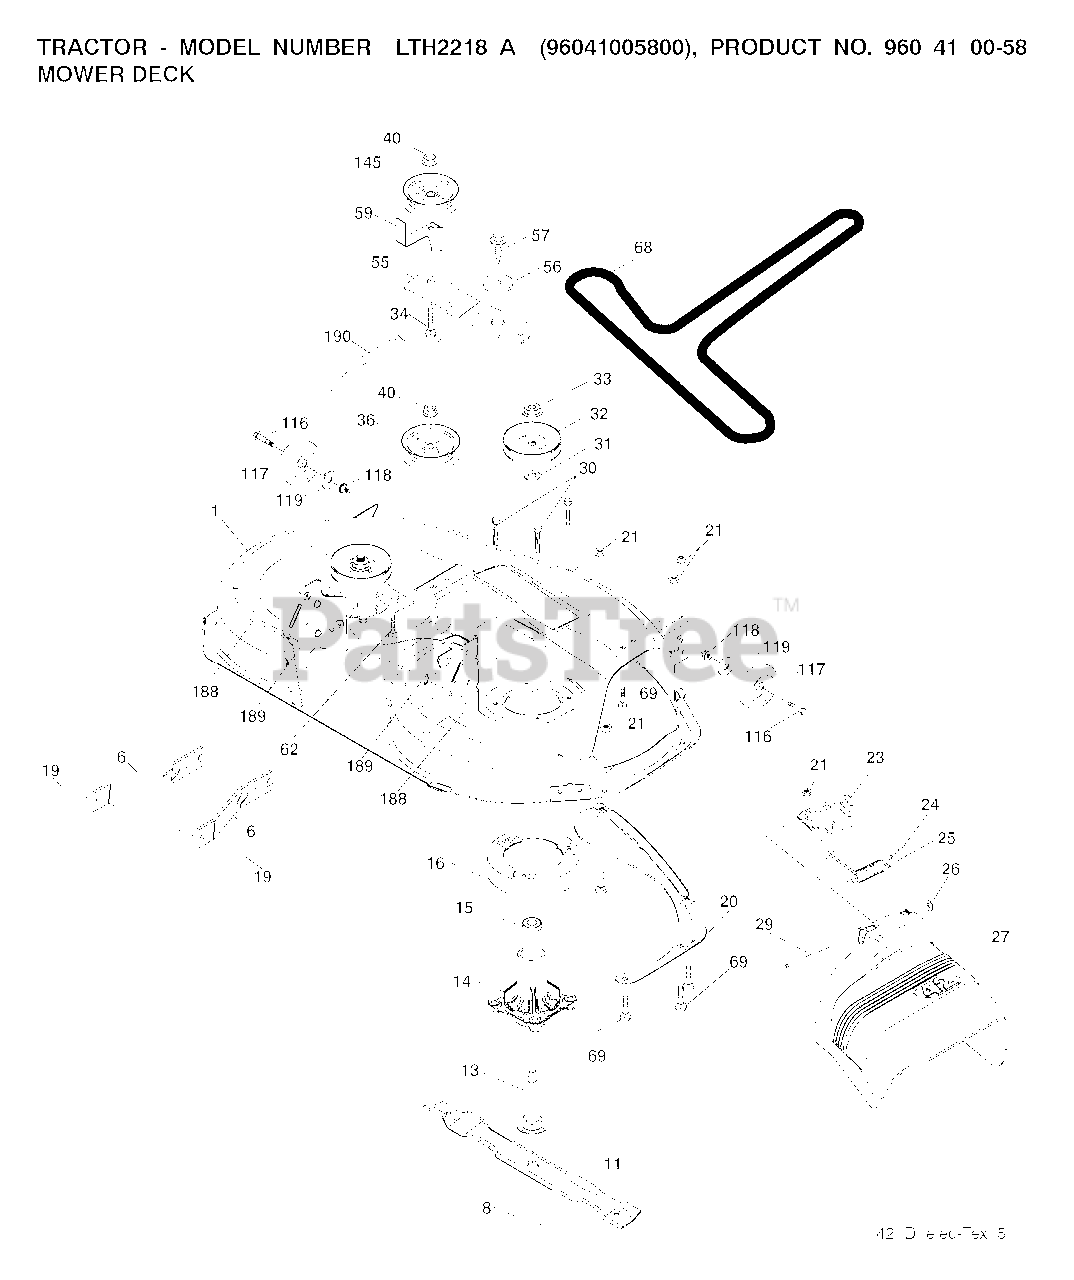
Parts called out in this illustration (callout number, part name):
1	DECK.WELDMENT.42"
6	ARM.SUSPENSION.MOWER.R
8	BOLT.WASHER.ASM.7/16-2
11	42" HI-LIFT BLADE
13	SHAFT.ASM.MDRL.N/GREASE.38
14	HOUSING MANDREL
16	STRIPPER, MWR ROUND
19	BOLT.SHOULDER
20	BAFFLE.VORTEX
21	LOCKNUT
23	BRKT.DEFLECTOR.38"2005+
24	CAP-SLEEVE LT
25	SPRING.TORSION.DEFLECT
26	NUT PUSH M
27	SHIELD.DEFLECTOR.MOWER.42"BLAC
29	ROD.HINGE
30	SCREW, WASHER HEAD
31	WASHER.SPACER.MANDREL
32	PULLEY/MANDREL
33	NUT.FLANGE.LOCK.TOP
34	BOLT.3/8-16X1.50
36	PULLEY.IDLER.48"PRIMARY
40	NUT LOCK FLG 3/8-16 UNC
55	IDLER.ARM
56	SPACER.RETAINER
57	SCREW 3/8-16X1
59	GUARD, BELT
62	BOLT
68	BELT V SECONDARY
69	BOLT
116	BOLT
117	WHEEL.GAGE.HALF.SPOKED
118	LOCKNUT
119	WASHER
145	PULLEY.IDLER.2006
188	STUD.FASTNER.W/ANTI-ROTATE
189	NUT LOCK HEX FLANGE 5/16-18
190	SPRING.MOWER.DRIVE.ELECTRIC
